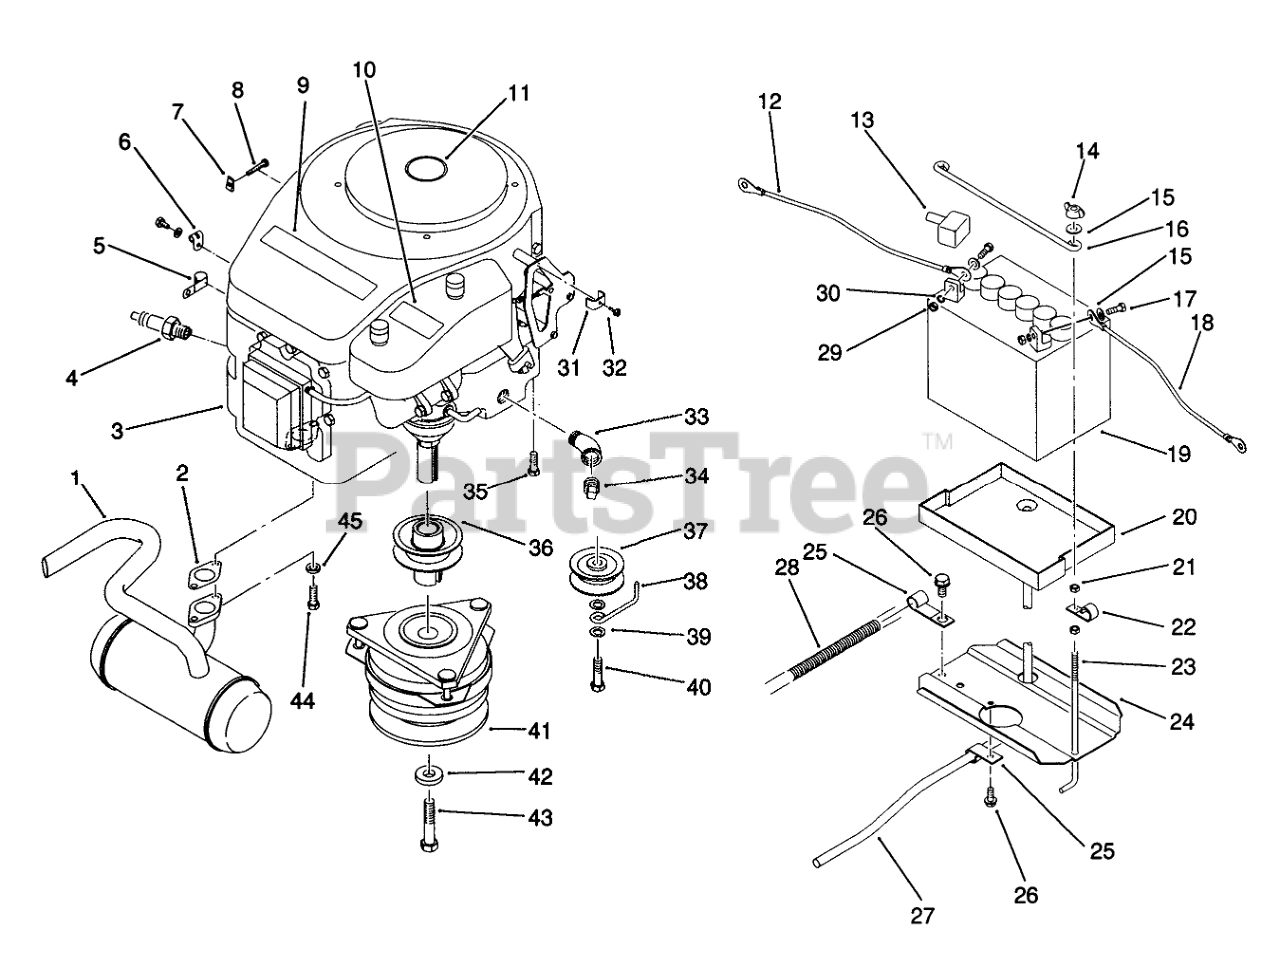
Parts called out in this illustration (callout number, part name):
1	MUFFLER
2	GASKET-EXHAUST
3	ENGINE-E14OV/11207
4	Plug-Spark
5	Clip
6	CLEVIS
7	J-CLIP
8	HHCS M8X1.25X15
9	DECAL-PWR PLUS
10	DECAL-14.0 POWER PLV
11	DECAL-TORO ENGINE
12	WIRE - 14" BLACK
13	Boot
14	Nut
15	Washer
16	ROD-BATTERY HOLD DWN
17	Screw-Cap Hex Hd
18	ASS'Y-WIRE
19	Battery
20	TRAY-BATTERY
21	Nut
22	CLAMP
24	Tray
25	J-CLIP
26	Bolt
27	TUBE-BATTERY DRAIN
28	WIRE-HARNESS
29	Nut
30	Washer-Lock
31	Clamp
32	#10 SHW TYPE B ST
33	Elbow-Street
34	Plug
35	SCREW-SELF TAP
36	PULLEY ENGINE GEA
37	IDLER PULLEY R
38	GUIDE-BELT
39	Washer
40	Bolt
41	Clutch
42	WASHER
43	HHCS-M10X1.5X110 ESL
44	HHCS M8X1.25X20
45	Washer-Lock
